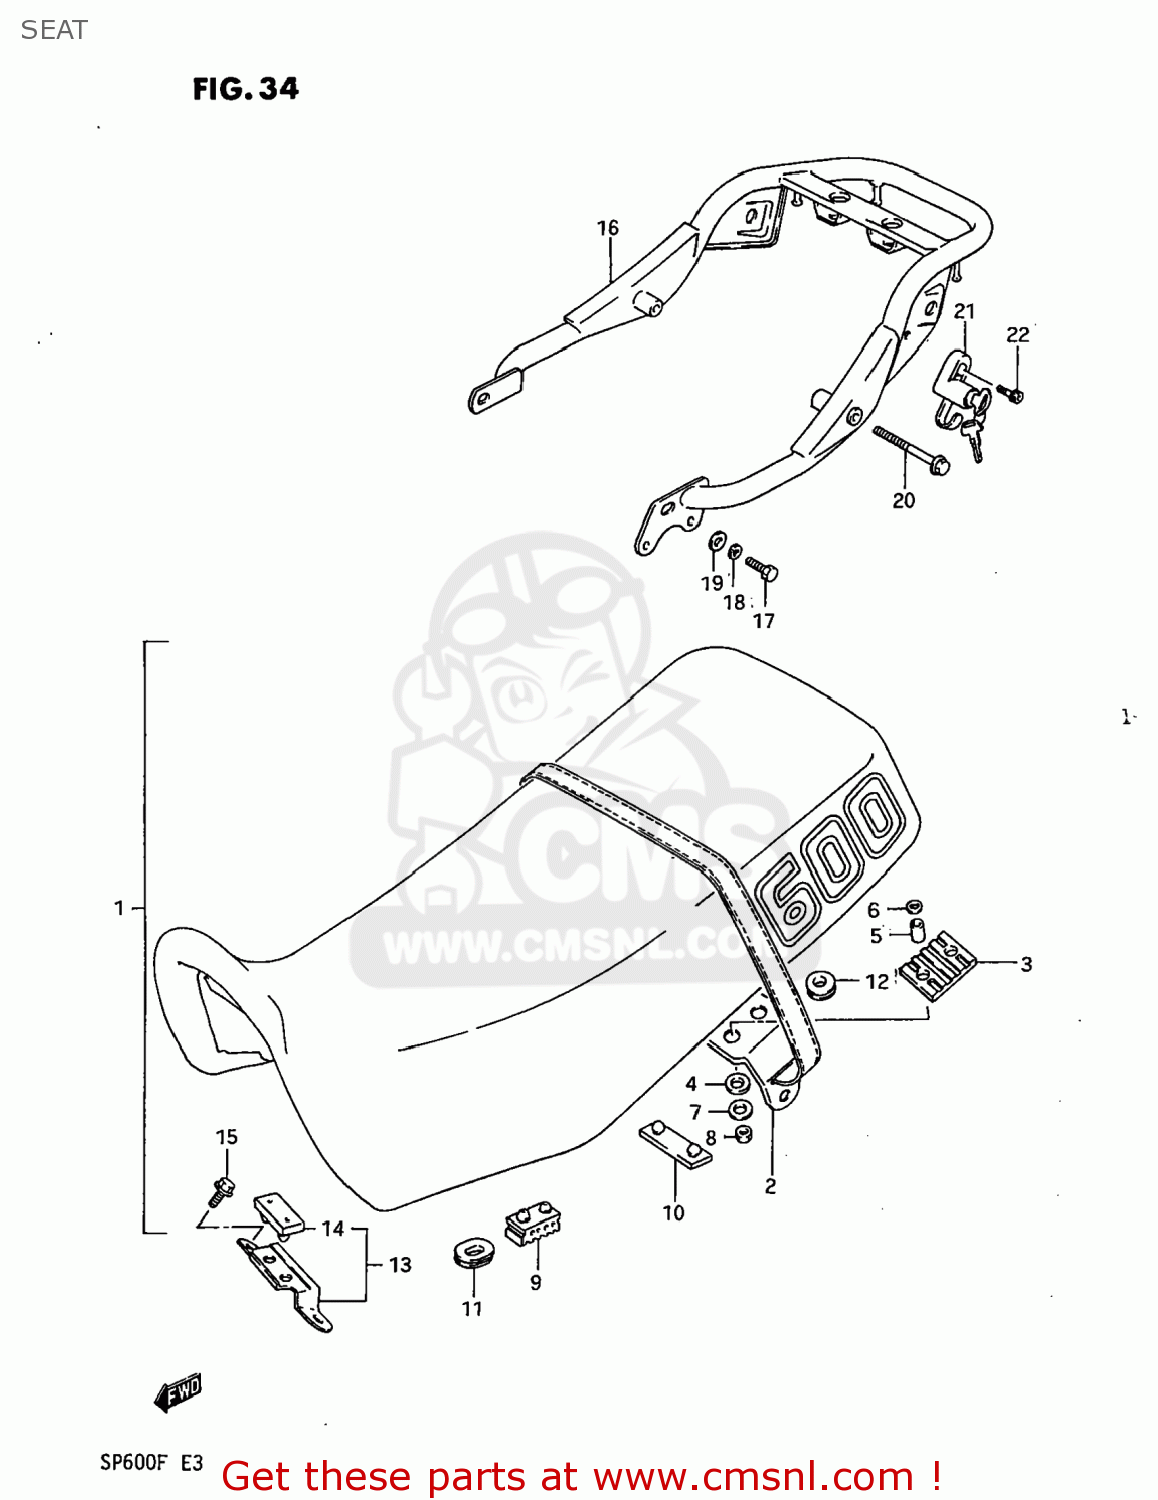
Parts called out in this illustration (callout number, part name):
1	SEAT ASSEMBLY
2	BAND,SEAT
3	CUSHION,SEAT FR
4	CUSHION,FR PLATE
5	SPACER,SEAT SUPPORT
6	WASHER
7	WASHER, LOWER
8	NUT
9	CUSHION,SEAT(40X20X15)
10	CUSHION
11	CUSHION
12	CUSHION
13	PLATE ASSY,SEAT FR HOOK
14	CUSHION
15	BOLT
16	CARRIER
17	BOLT
18	LOCK WASHER
19	WASHER
20	BOLT 8X60
21	LOCK SET
22	BOLT
